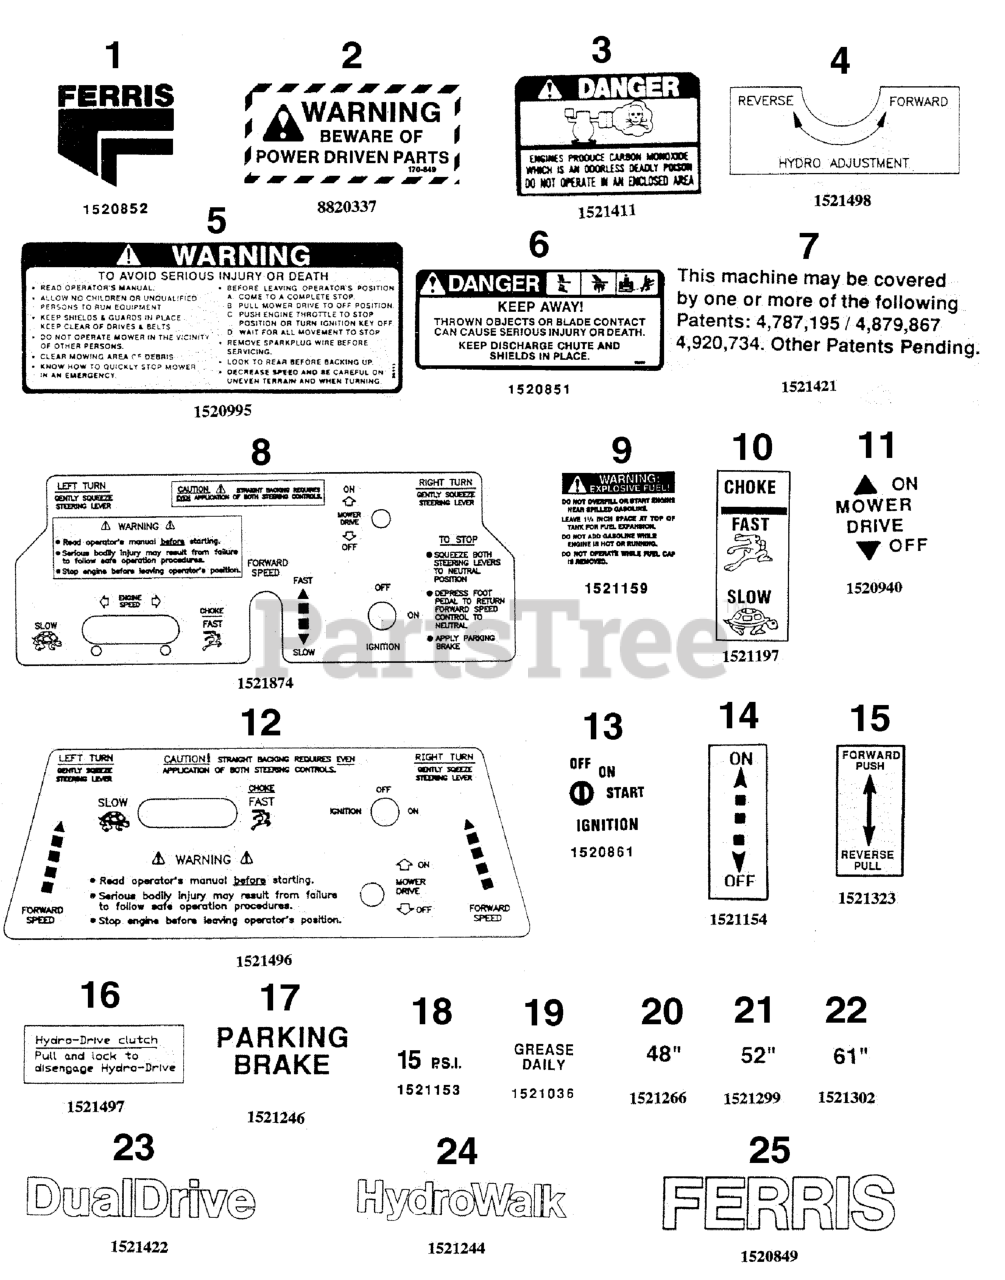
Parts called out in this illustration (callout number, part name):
1	DECAL, Ferris Logo, 10-3/4"
2	DECAL, Warning
3	DECAL, Danger, Carbon Monoxide
4	DECAL, Hydro Adjustment
5	DECAL, WARNING Operation
6	DECAL, DANGER DO NOT OPERATE W/O DEFLECT
7	DECAL, Patent
8	DECAL, Operation
9	DECAL, EXPLOSIVE FUEL
10	DECAL, Throttle Control
11	DECAL, Mower Drive On / Off
12	DECAL, Operation
13	DECAL, Ignition
14	DECAL, PTO Switch
15	DECAL, Forward-Reverse
16	DECAL, Hydro-Drive Clutch
17	DECAL, Parking Brake
18	DECAL, 15 P.S.I.
19	DECAL, Grease Daily
20	DECAL, 48
21	DECAL, 52
22	DECAL, 61"
23	DECAL, Dual Drive
24	DECAL, HydroWalk, Word
25	DECAL, FERRIS TEXT & LOGO
